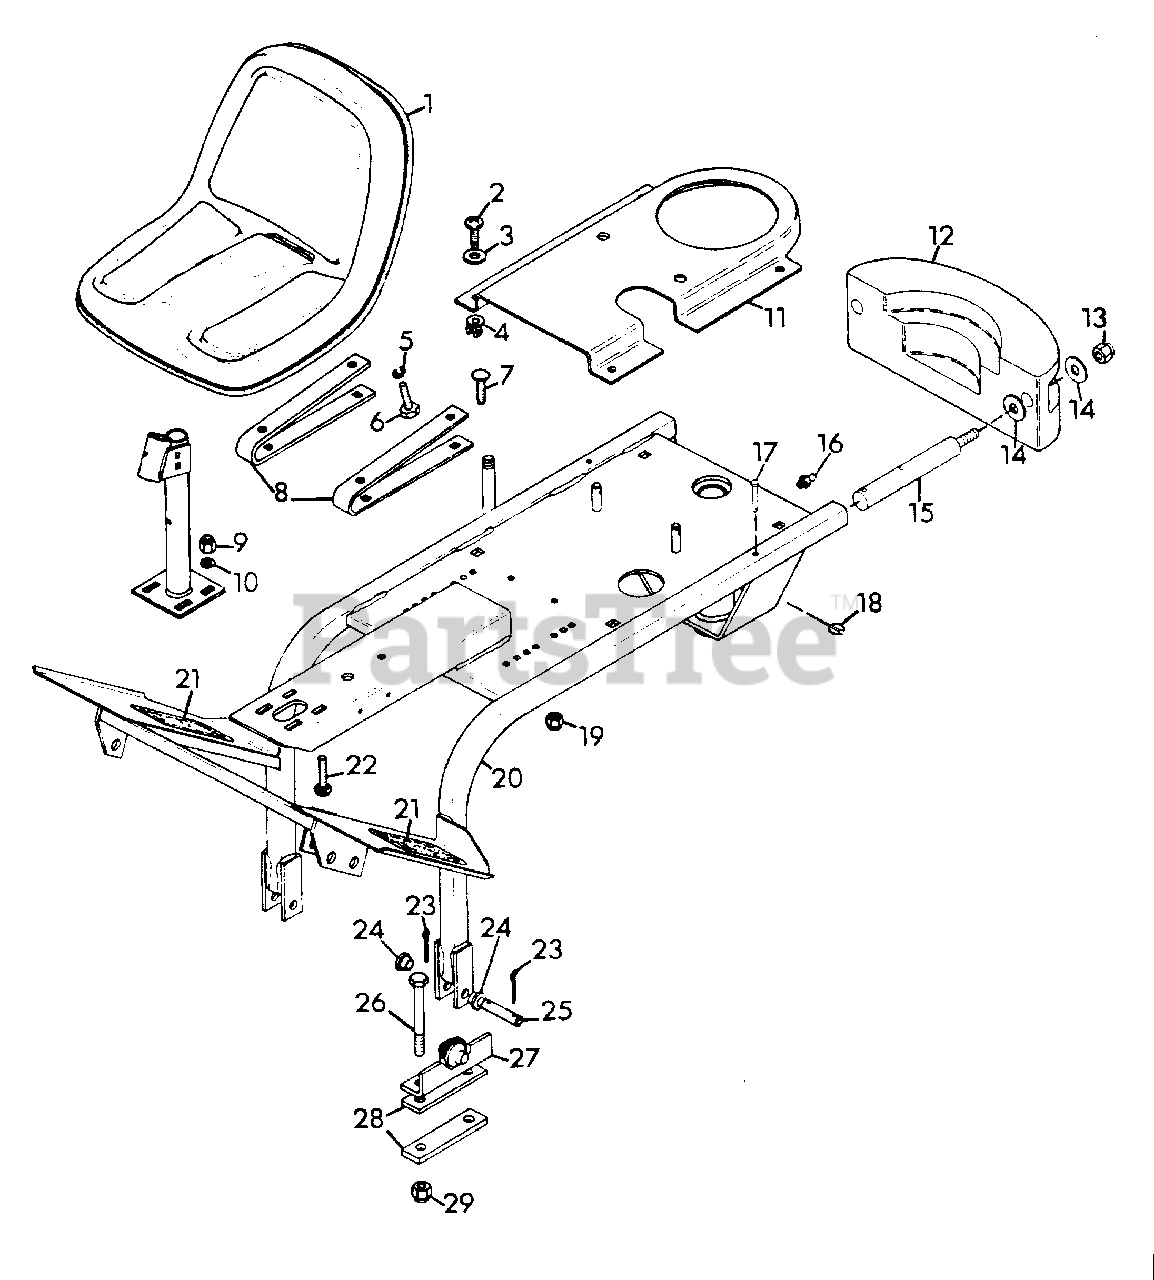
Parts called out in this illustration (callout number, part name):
1	SEAT, HIGH BACK
2	SCREW, TAPPING 1/4-20X.625 PHD
3	WASHER, FLAT .344X.688X.065
4	GROMMET, PLASTIC
5	WASHER, LOCK 5/16 REG.
6	BOLT, HEX 5/16-18X.75
7	BOLT, CARRIAGE 5/16-18X1.00
8	SPRING, SEAT
9	NUT, LOCK 3/8-16
10	WASHER, FLAT .406X.812X.065
11	COVER, CHAIN
12	WEIGHT, PRO MASTER-50
13	NUT, LOCK 3/4-10
14	WASHER, FLAT .813X2.0X.148
15	SHAFT, WEIGHT
16	FITTING, LUBE 1/4-28
17	PIN, CLEVIS .375X2.62
18	PIN, KLIK
19	NUT, LOCK 5/16-18
20	FRAME, O.F.C.
21	COVER, LARGE FOOTBOARD
22	BOLT, 3/8-16X1.00 RD HD SQ NK
23	PIN, COTTER .125X1.500
24	BUSHING
25	PIN, .750X3.3
26	BOLT, HEX 1/2-13X5.50
27	WELDMENT, BRACKET MOUNTING
28	PLATE, AXLE
29	NUT, LOCK 1/2-13
NS	DECAL, GRAVELY LOGO
NS	DECAL, PRO MASTER-50(CONTROLS)
NS	DECAL, AMERICA
NS	DECAL, PRO MASTER LOGO
